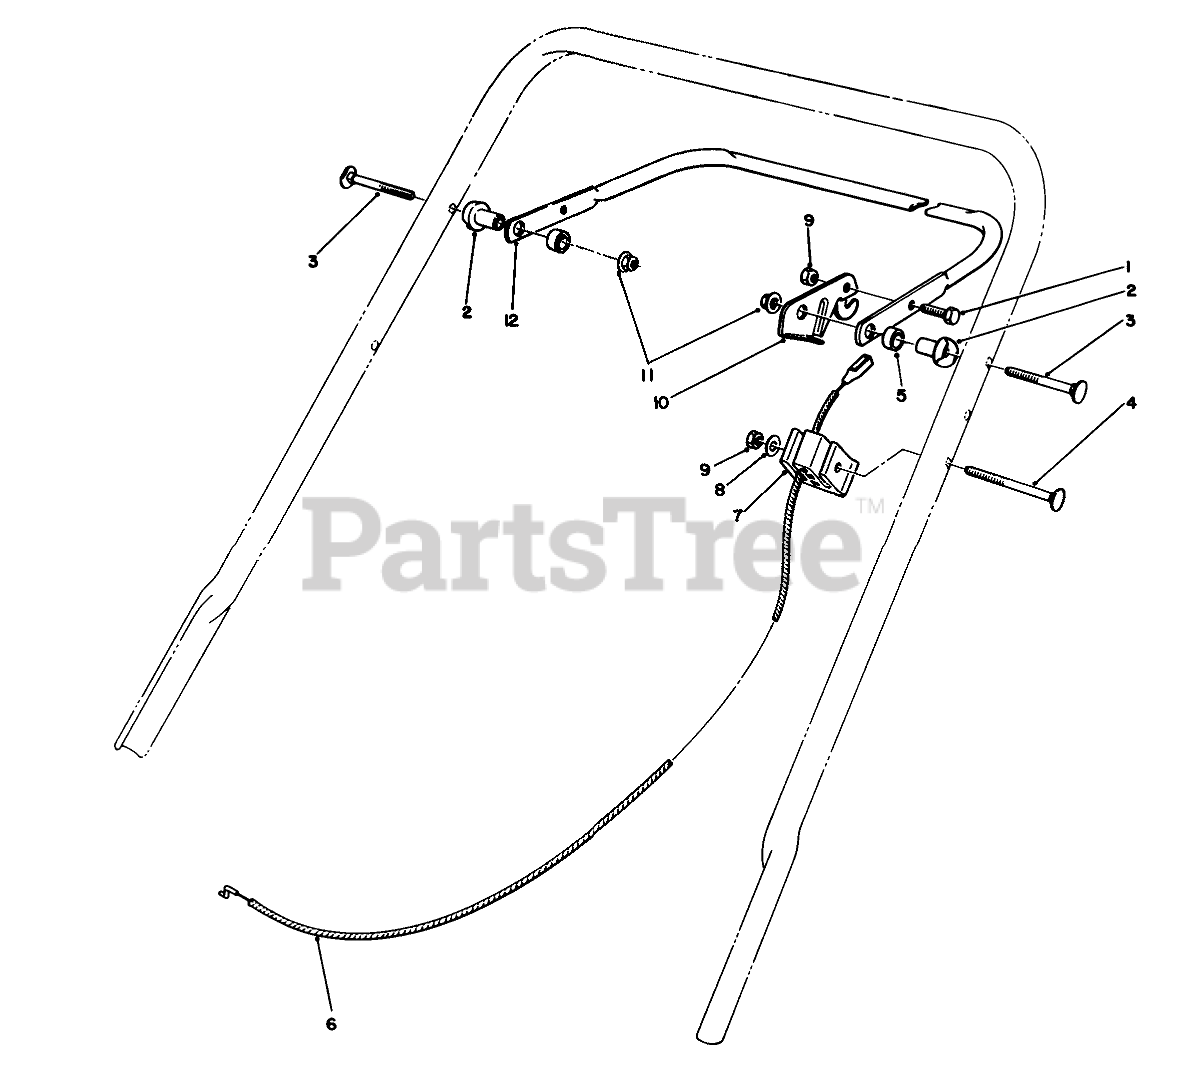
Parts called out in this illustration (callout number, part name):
1	SCREW-HH
2	SPACER-SUPPORT
3	5/16-18 X 2 HNDLE SCREW
4	HANDLE SCREW
5	SPACER-NYLON
6	BRAKE CONTROL
7	SUPPORT-CABLE
8	WASHER-FLAT
9	NUT-LOCK, NI
10	LEVER-CONTROL
11	NUT-LOCK, NI
12	Bar-Control
